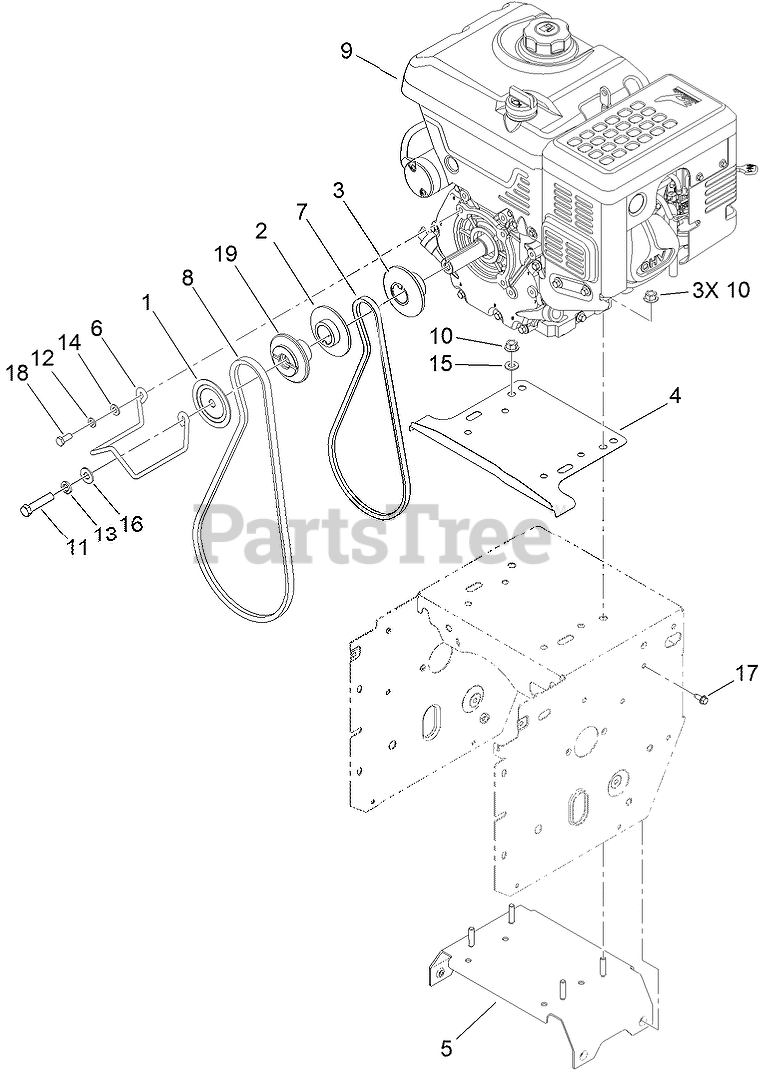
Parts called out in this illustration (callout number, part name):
1	SHEAVE-HALF, IMPELLER
2	PULLEY-ENGINE, TRACTION
3	SHEAVE-HALF, TRACTION
4	SHIELD-DRIVE
5	FRAME BRACE ASM
6	GUIDE-BELT
7	BELT-V
8	BELT-V
9	ENGINE-175FDS-1
10	NUT-FLANGE
11	SCREW-HH
12	WASHER-LOCK
13	WASHER-LOCK
14	WASHER-PLAIN
15	WASHER-FLAT
16	WASHER-FLAT
17	SCREW-HWH
18	SCREW-HH
19	PULLEY-ENGINE, IMPELLER
